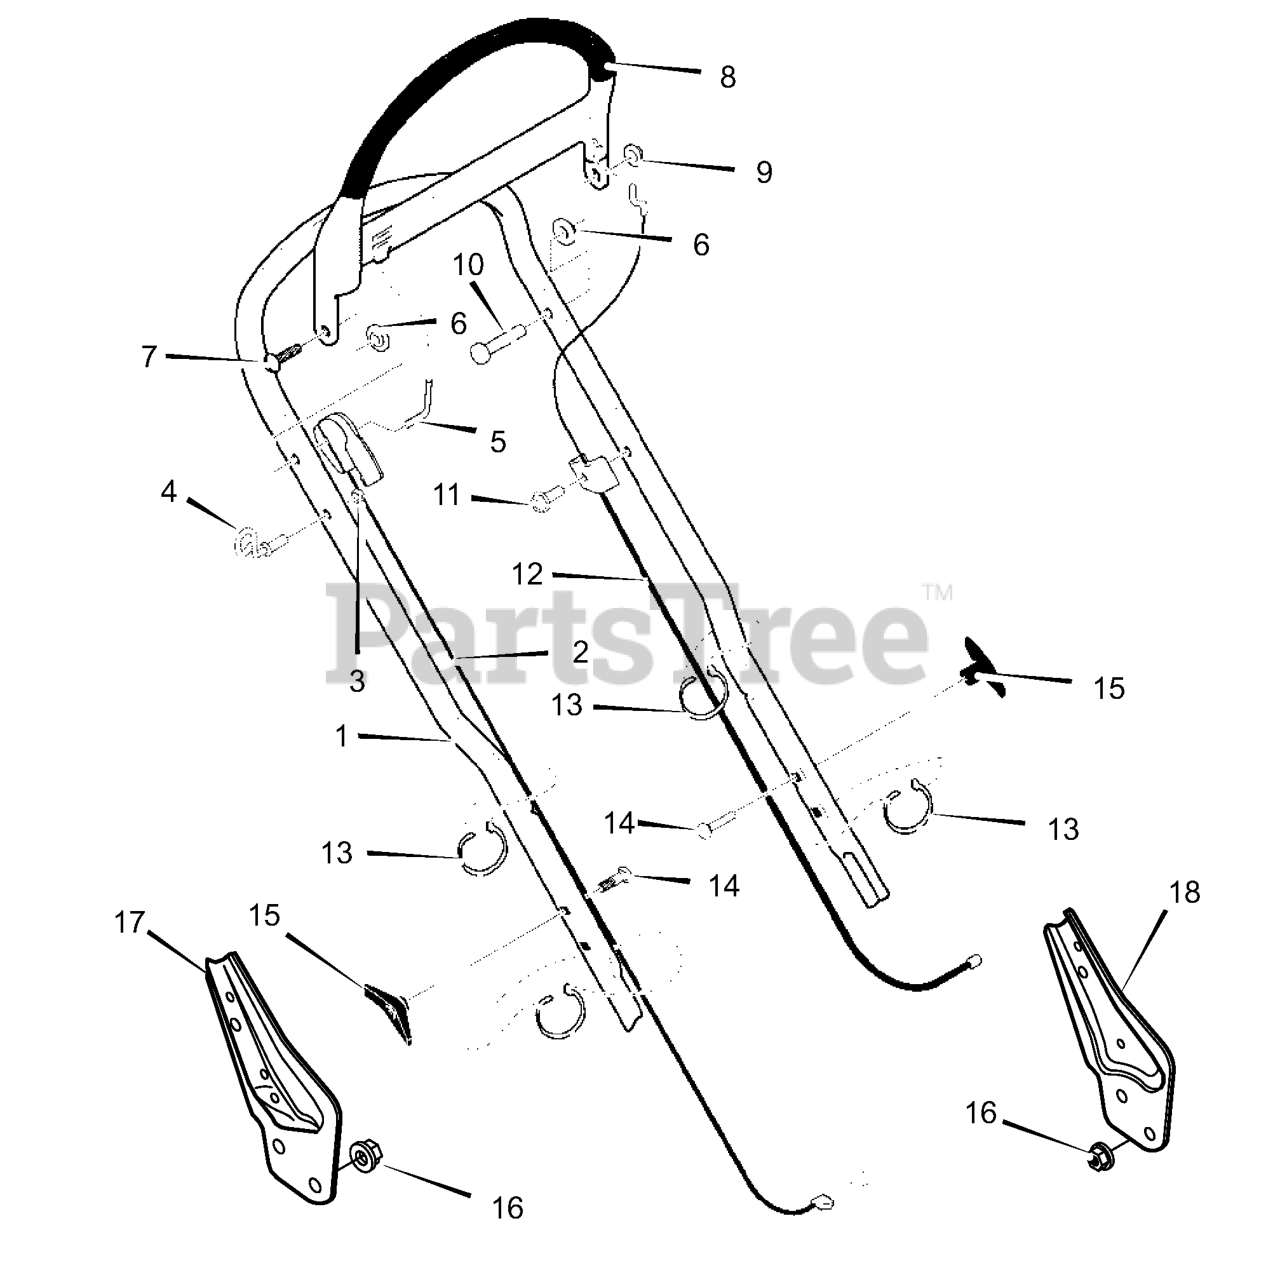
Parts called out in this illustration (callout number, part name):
1	Handle, Upper (Black)
2	Control, Drive
3	Locknut
4	Guide, Rope
5	Rod, Drive Link
8	Lever, Stop
9	Push-On Cap
10	Pin, Clevis
12	Cable, Stop
13	Strap, Tie
14	Bolt, Carriage
15	Wingnut
16	Nut
17	Bracket, Right Handle
18	Bracket, Left Handle
